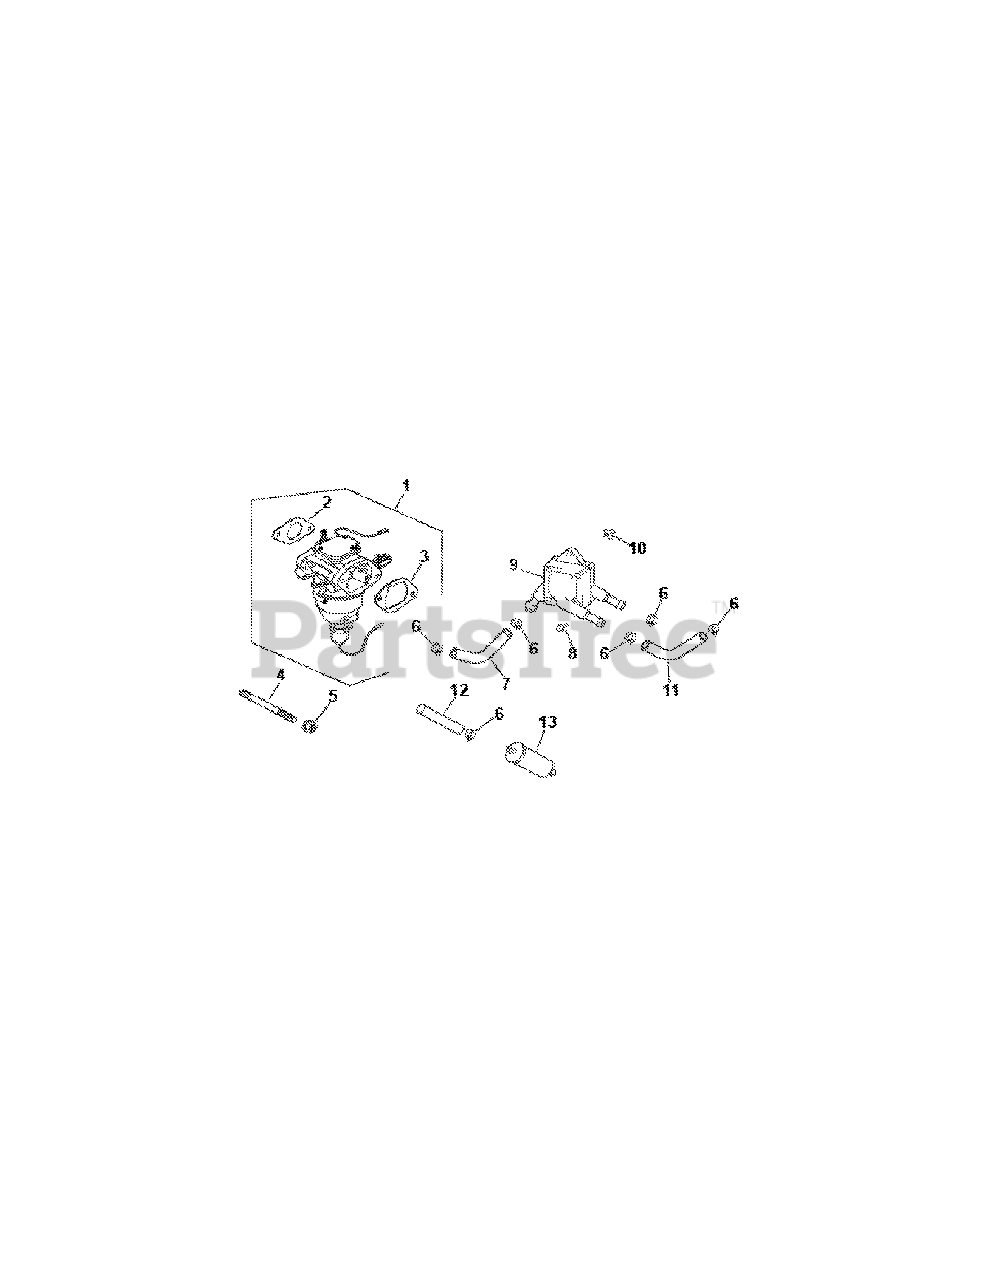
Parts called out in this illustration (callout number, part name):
1	Carburetor w/Gaskets
2	Carburetor Gasket
3	Air Cleaner Base Gasket
4	Intake Manifold Stud
6	Hose Clamp
7	Fuel line 12.5"
10	Plastic Nut
11	Fuel Line 11"
12	Fuel Line 3.5"
13	Fuel Filter
